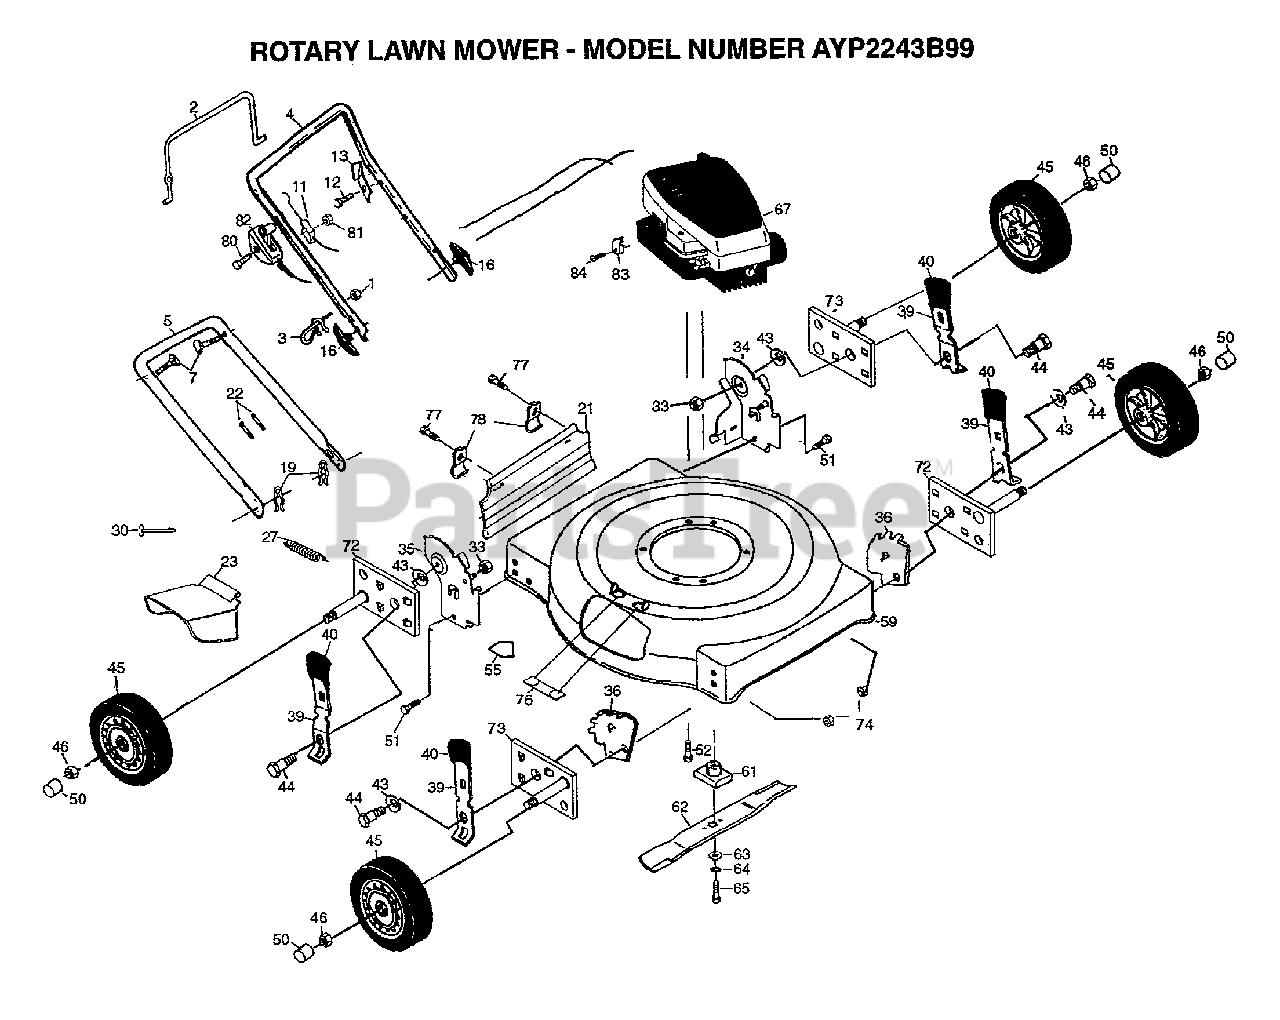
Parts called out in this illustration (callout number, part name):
2	CONTROL BAR PM
3	ROPE GUIDE
5	LOWER HANDLE
7	BOLT.HANDLE.LM
11	"CABLE.MZR.47"""
12	TAPPING SCREW
13	"BRKT,UPSTOP"
16	"NUT,WING PM"
19	HAIRPIN COTTER
21	"SKIRT.REAR.22SD/ECON.21"""
23	GUARD.DISCHARGE
27	HINGE.SPRING
30	HINGE.ROD.22SD
33	LOCKNUT
34	BRKT.HDLE/ADJ.LT
35	BRKT.HDLE/ADJ.RT
36	WHEEL.BRKT.ADJ.
39	SPRING.SELECTOR.5/9POS
40	KNOB PM
43	WASHER.BELLEVELLE
44	SHOULDER BOLT
45	WHEEL.ASM
46	HEX FLANGE LOCKNT
50	HUB CAP-PLASTIC
51	SCREW 1/4X20
52	BOLT.ENG.3/8-16
55	DECAL-DANGER PM
59	KIT.HSG.22SD.PUSH.RED
61	ADAPTOR.BLADE.LM
62	"BLADE.MULCH.22"""
63	"WASHER,HARDEN"
64	LOCKWASHER
65	SCREW
72	ARM.ASM.AXLE.RR/LF.
73	ARM.ASM.AXLE.LR/RF
74	LOCKNUT
76	CLIP.CLOSECUT.22SD
77	TAPPING SCREW
78	"BRKT,DEFL PM"
80	SCREW.HXHD.WASH.
82	"CONTROL, THROTTLE"
83	CABLE CLAMP
84	SCREW PM
